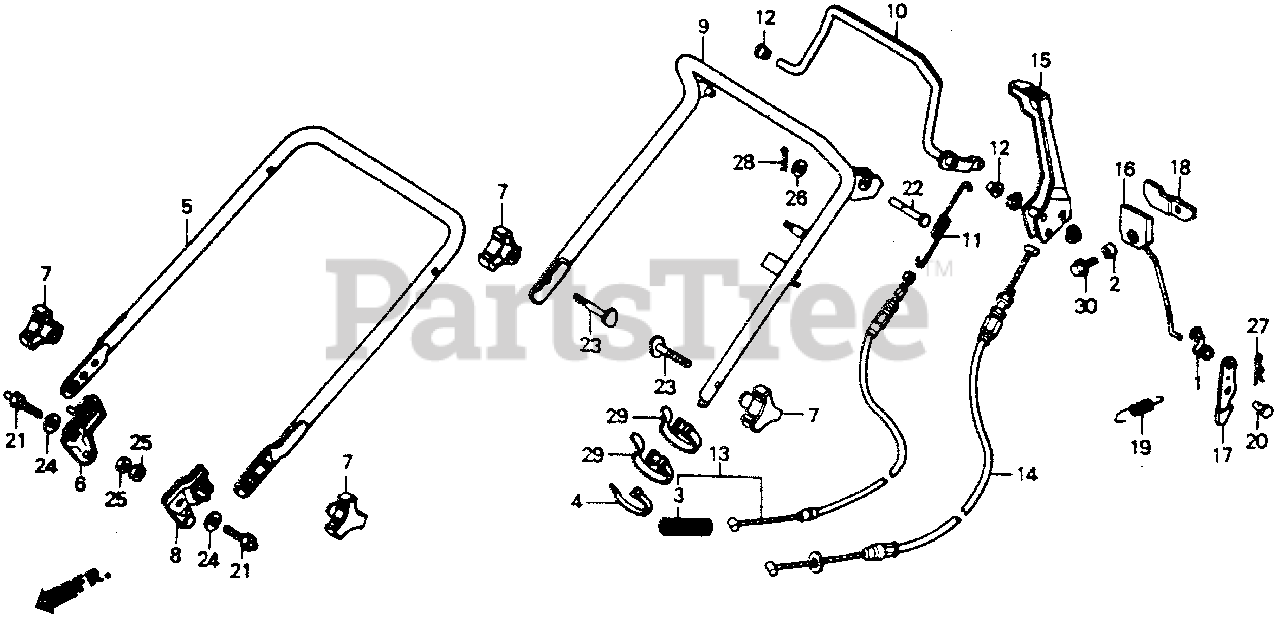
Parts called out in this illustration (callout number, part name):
1	JOINT, ROD
2	COLLAR, FAN
3	SPRING, CLUTCH RETURN
4	TIE, CABLE (NATURAL 2.4X92) Use up to Frame SN 1300359.
5	HANDLE (LOWER)
6	STAY, R. HANDLE
7	GRIP, HANDLE JOINT (UPPER)
8	STAY, L. HANDLE
9	PIPE, HANDLE (UPPER) *NH105* (MAT BLACK)
10	LEVER, CLUTCH (NOT AVAILABLE)
11	SPRING, CLUTCH
12	BUSH, CLUTCH LEVER
13	CABLE, SELF
14	CABLE, ROTO-STOP
15	LEVER, ROTO-STOP (NOT AVAILABLE)
16	ROD, RATCHET PUSH (NOT AVAILABLE)
17	LEVER, LOCK (NOT AVAILABLE)
18	PLATE, PUSH ROD (NOT AVAILABLE)
19	SPRING, RATCHET RETURN
20	PIN, SEAT HINGE
21	BOLT, HANDLE HOOK
22	PIN, CLUTCH LEVER
23	BOLT, HANDLE HOLDER (8X41)
23	BOLT (8X41)
24	WASHER, SPECIAL (22X8.5X2)
25	NUT, SELF-LOCK (8MM)
25	NUT, HEX. (8MM)
26	WASHER, PLAIN (8MM)
27	PIN, LOCK (6MM)
28	PIN, LOCK (8MM)
29	TIE, CABLE
29	BAND B2, CABLE HARNESS
30	BOLT, FLANGE (6X10)
